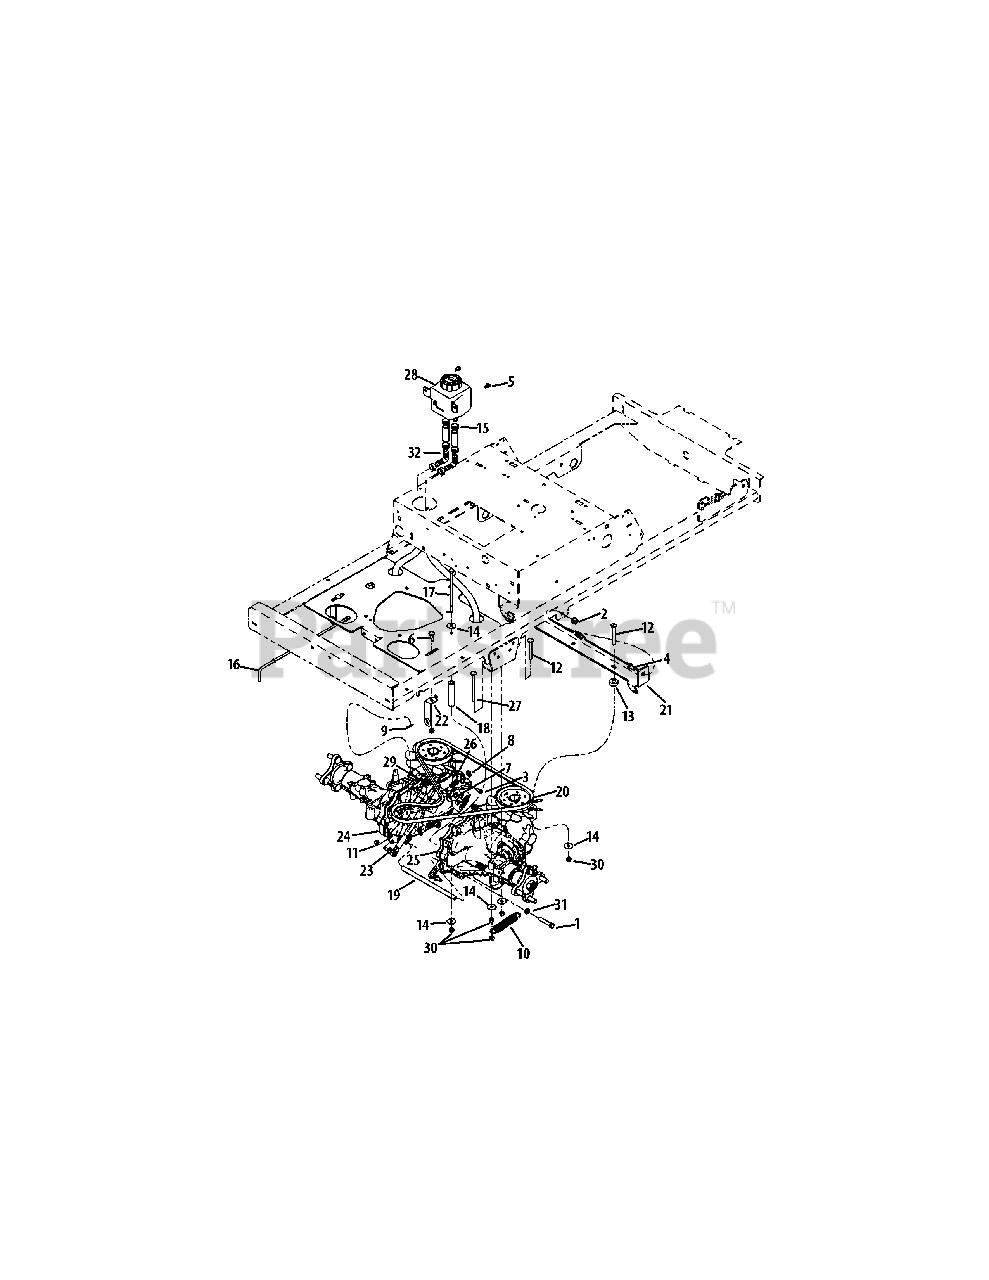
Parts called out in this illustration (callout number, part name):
1	Hex Screw, 3/8-16 x 2.00
2	Flange Counterlock Nut, 3/8-16
3	Hex Screw, 1/4-20 x .620
4	Carriage Bolt, 3/8-16 x .75
5	Hex Flange Screw, 1/4-20 x .500
6	Carriage Bolt, 5/16-18 x 1.00
7	Shoulder Bolt, 1/4-28 x .38 x .465
8	Flange Toplock Nut, 1/4-20
9	Hair Pin, 1/8 x 1.125 x .072
10	Extension Spring, .865 x 4.7 x .12
11	Nylock Nut, M8-1.25
12	Carriage Bolt, 5/16-18 x 2.75
13	Spacer, .406 x 1.00 x .38
14	Washer, .313 x 1.06 x .062
15	Hose Clamp, .750
16	Pump Relay Rod
17	Hex Screw, 5/16-18 x 6.00
18	Spacer, .375 x .750 x 3.30
19	Transmission Support Tube
20	V-Belt
21	Transmission Bracket Weldment
22	Neutral Bracket
24	LH Transmission
25	RH Transmission
26	Control Arm Damper Bracket
27	Carriage Bolt, 5/16-18 x 4.0
28	Expansion Tank Assembly
29	Jam Nut, 1/4-28
30	Hex Lock Nut, 5/16-18
31	Lock Washer, 3/8
